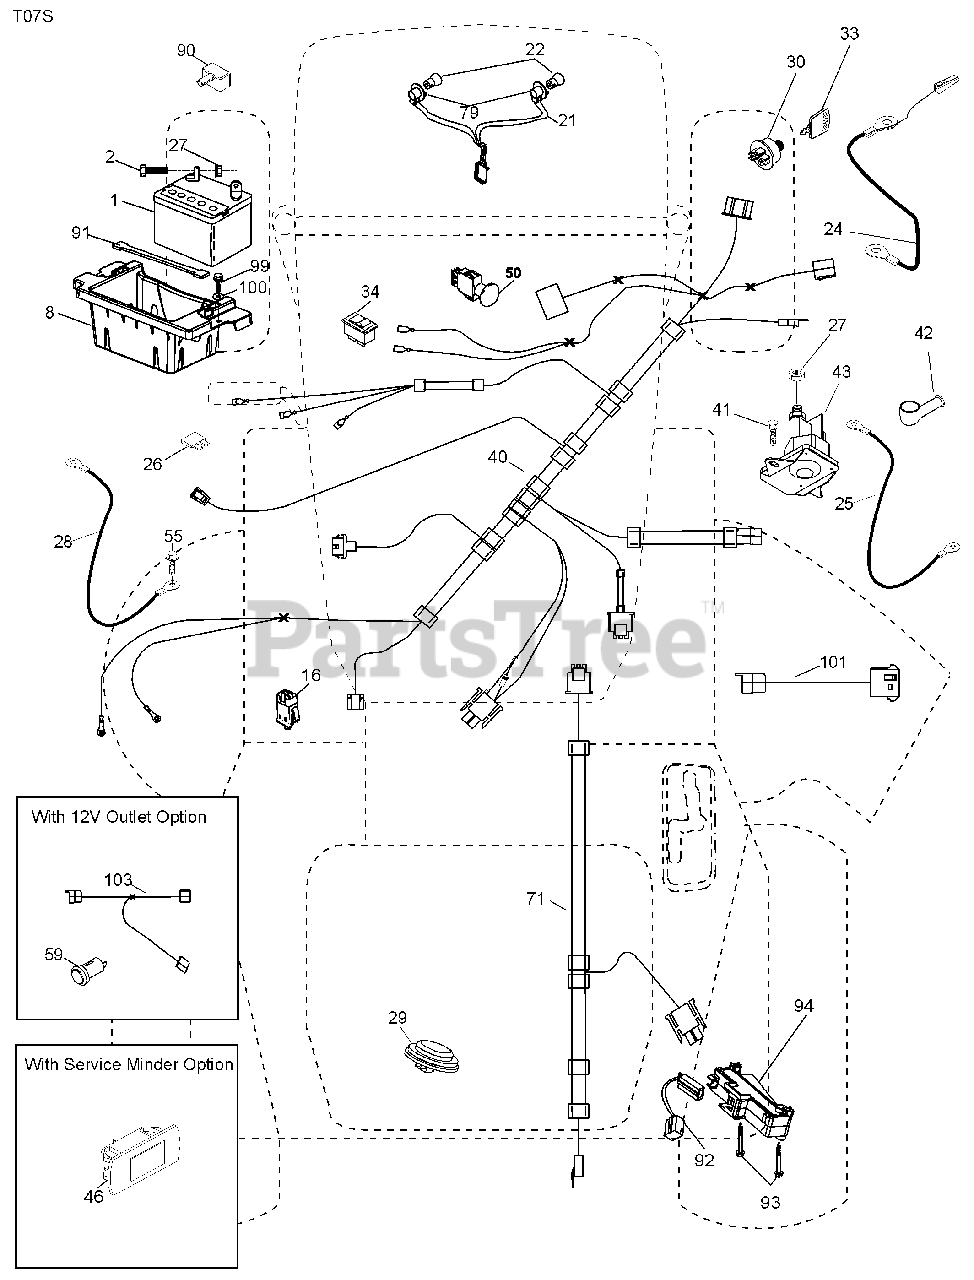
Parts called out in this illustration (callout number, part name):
1	Battery
2	Bolt Hex Hd 1/4-20 unc x 3/4
8	Battery Box
16	Switch Interlock
21	Harness Socket Light
22	Bulb, Light #1156
24	Cable Battery
25	Cable Starter
27	Nut Keps Hex 1/4-20 unc
28	Cable Ground 21" Blk 6 Ga.
29	Switch Seat
30	Switch Ign
34	Switch Light/Reset
40	Harness Ign. Dash
41	Screw 1/4-20 unc x 1/2
42	Cover Terminal Red
43	Solenoid
46	Gauge Hourmeter
50	Switch PTO
55	Screw Thdrol 5/16-18 x 3/4
59	Outlet 12-Volt
71	Harness Ign
79	Socket Asm. Bulb Twistlock
90	Cover Terminal Battery
91	Strap Battery
92	Harness Pigtail Console ROS
93	Screw Plastite 10-14 x 2.0
94	Module Reverse ROS
99	Screw Hexwsh Thdrol 1/4-20 x 3/4
100	Washer 9/32 x 7/8 x 16 Ga.
101	Pigtail MATNLK New Horn
103	Harness Pigtail 12V Outlet
